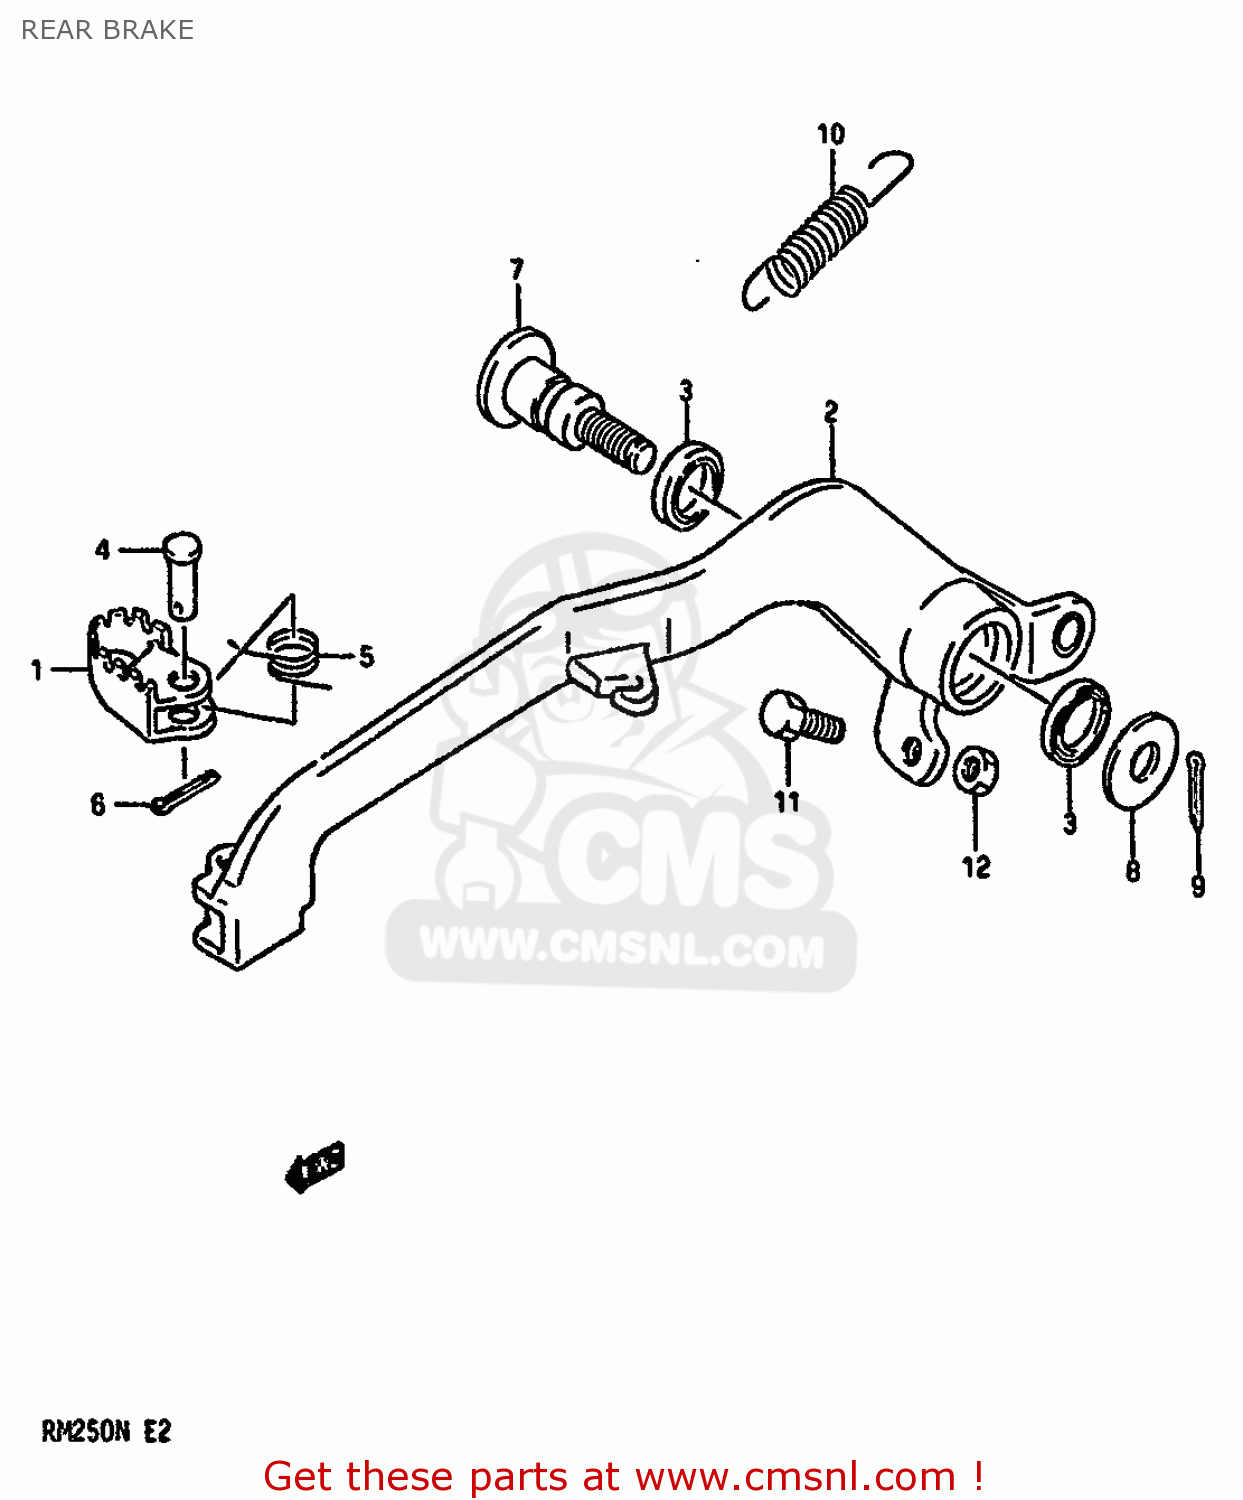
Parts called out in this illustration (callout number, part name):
1	PEDAL,BRAKE
2	ARM COMP,BRAKE PEDAL
3	SEAL,OIL(15X21X3)
4	PIN(6X23.5)
5	SPRING
6	PIN
7	SHAFT,BRAKE PEDAL
8	WASHER
9	PIN 20X20
10	SPRING
11	BOLT(6X23)
12	NUT 6MM
